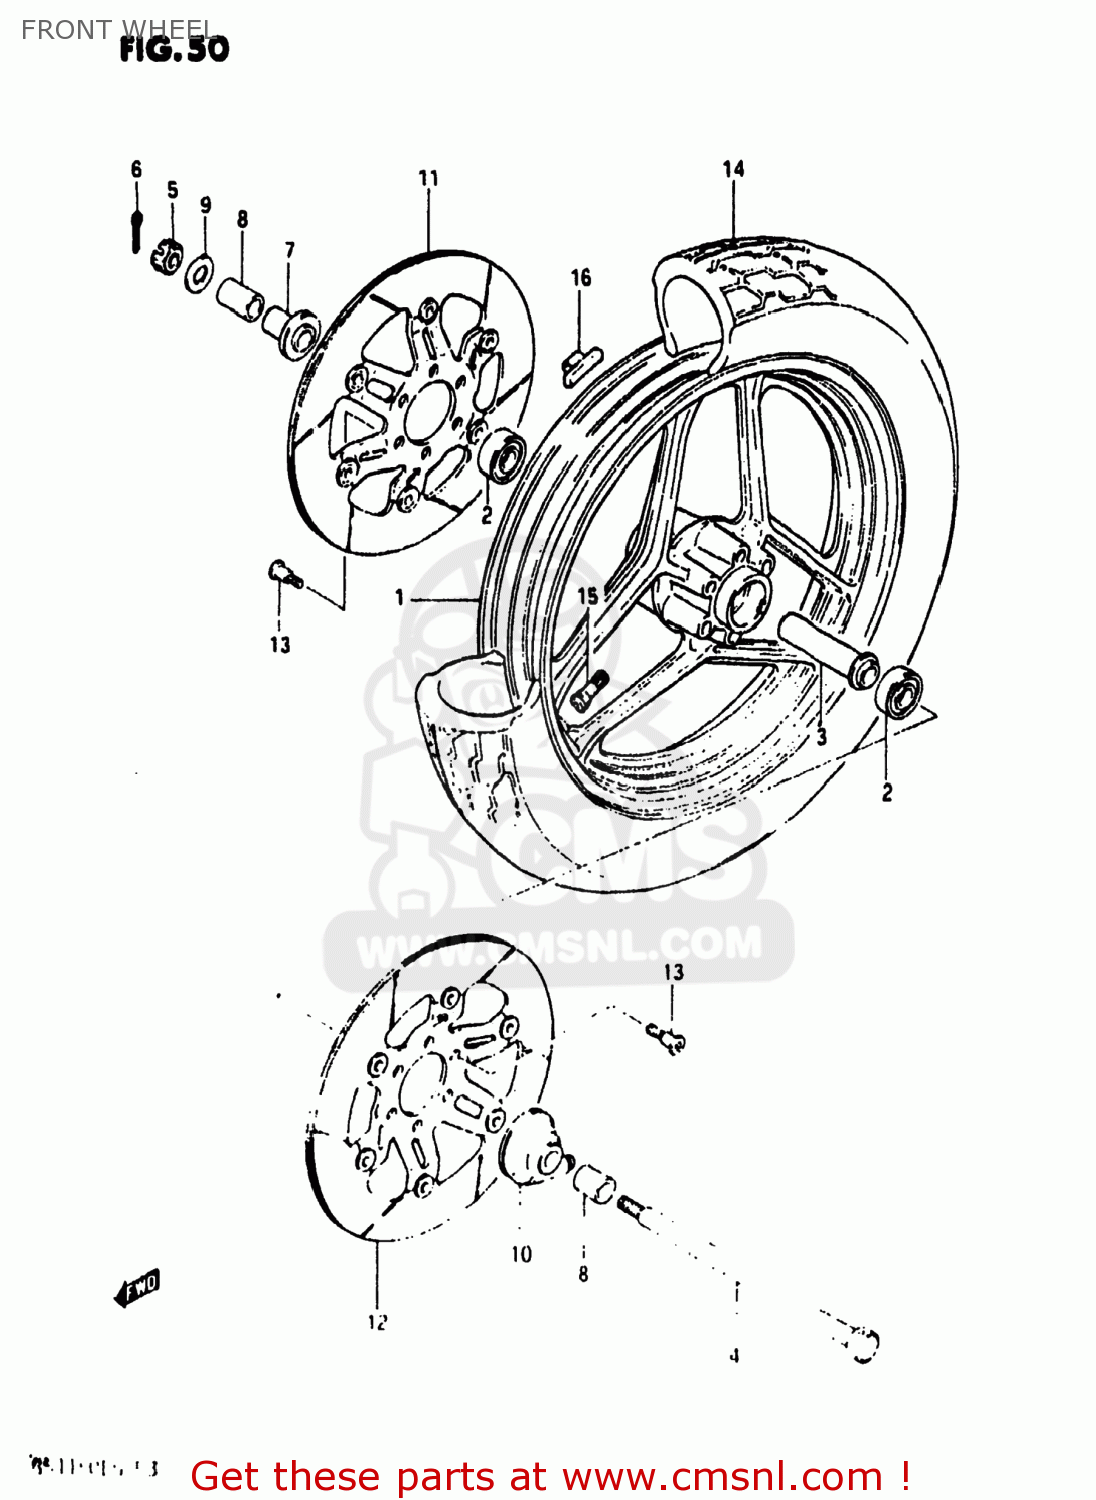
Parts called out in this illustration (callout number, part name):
1	CASTING WHEEL,FRONT 2.50
2	BEARING
3	SPACER,FRONT HUB BEARING
4	AXLE,FRONT
5	NUT 12MM
6	COTTER PIN
7	SPACER,FR AXLE,R
8	SPACER(15X22X30)
9	WASHER
10	BOX ASSY,SPEEDOMETER GEAR
11	DISC,BRAKE
12	DISC,BRAKE
13	BOLT
14	TIRE,FRONT
15	VALVE,TIRE
16	BALANCER,WHEEL
